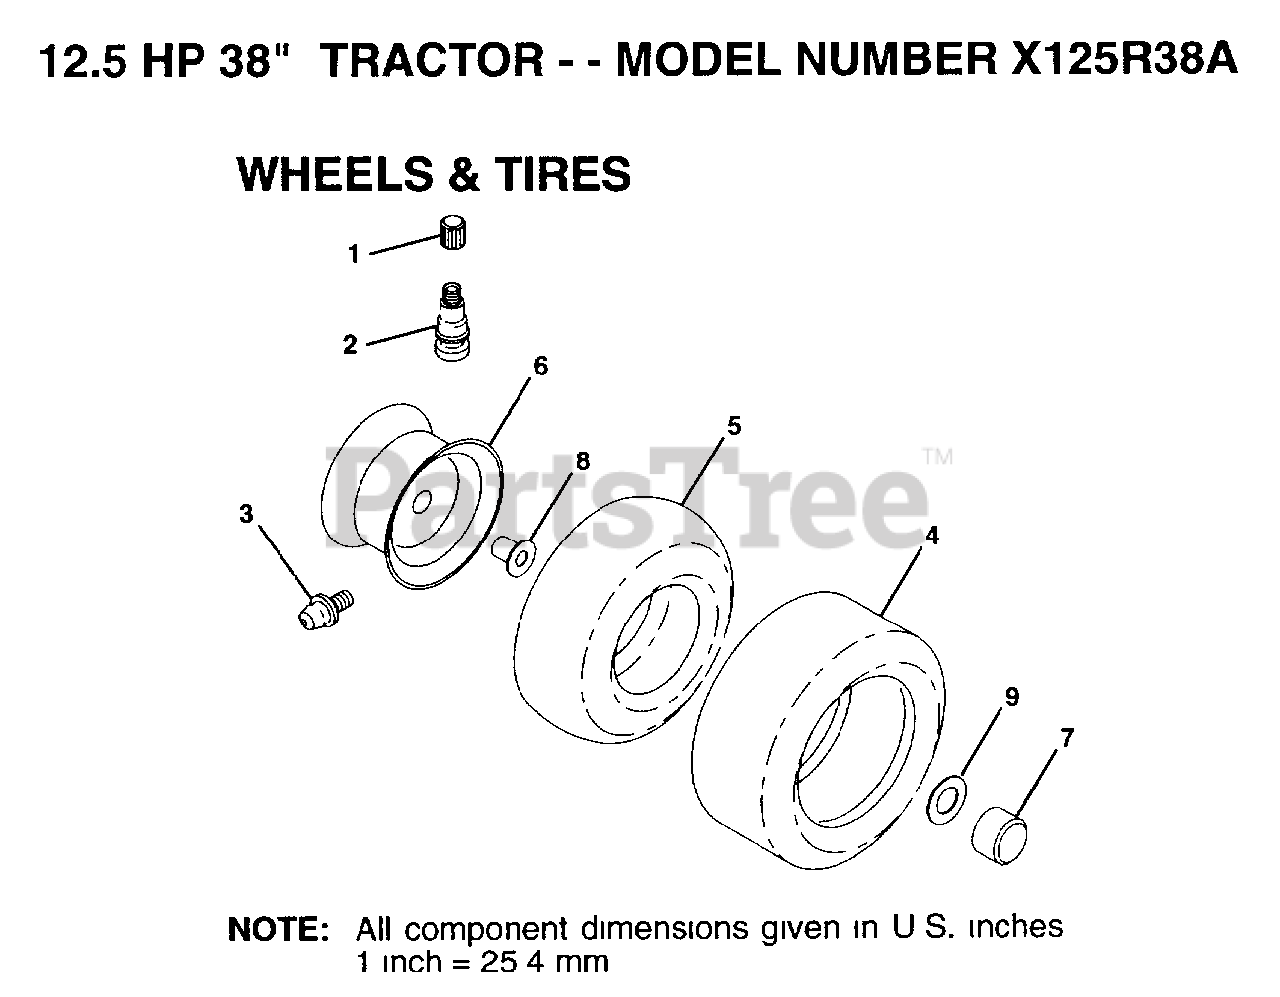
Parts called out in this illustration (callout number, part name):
1	VALVE CAP
2	VALVE STEM LT
3	FITTING LT
5	TUBE.5.3/4.5/6
5A	TUBE.16X6.5/7.5-8
6	"RIM.ASM.6""FRT"
7	HUB CAP
8	"FLANGE, BEARING"
9	WASHER
